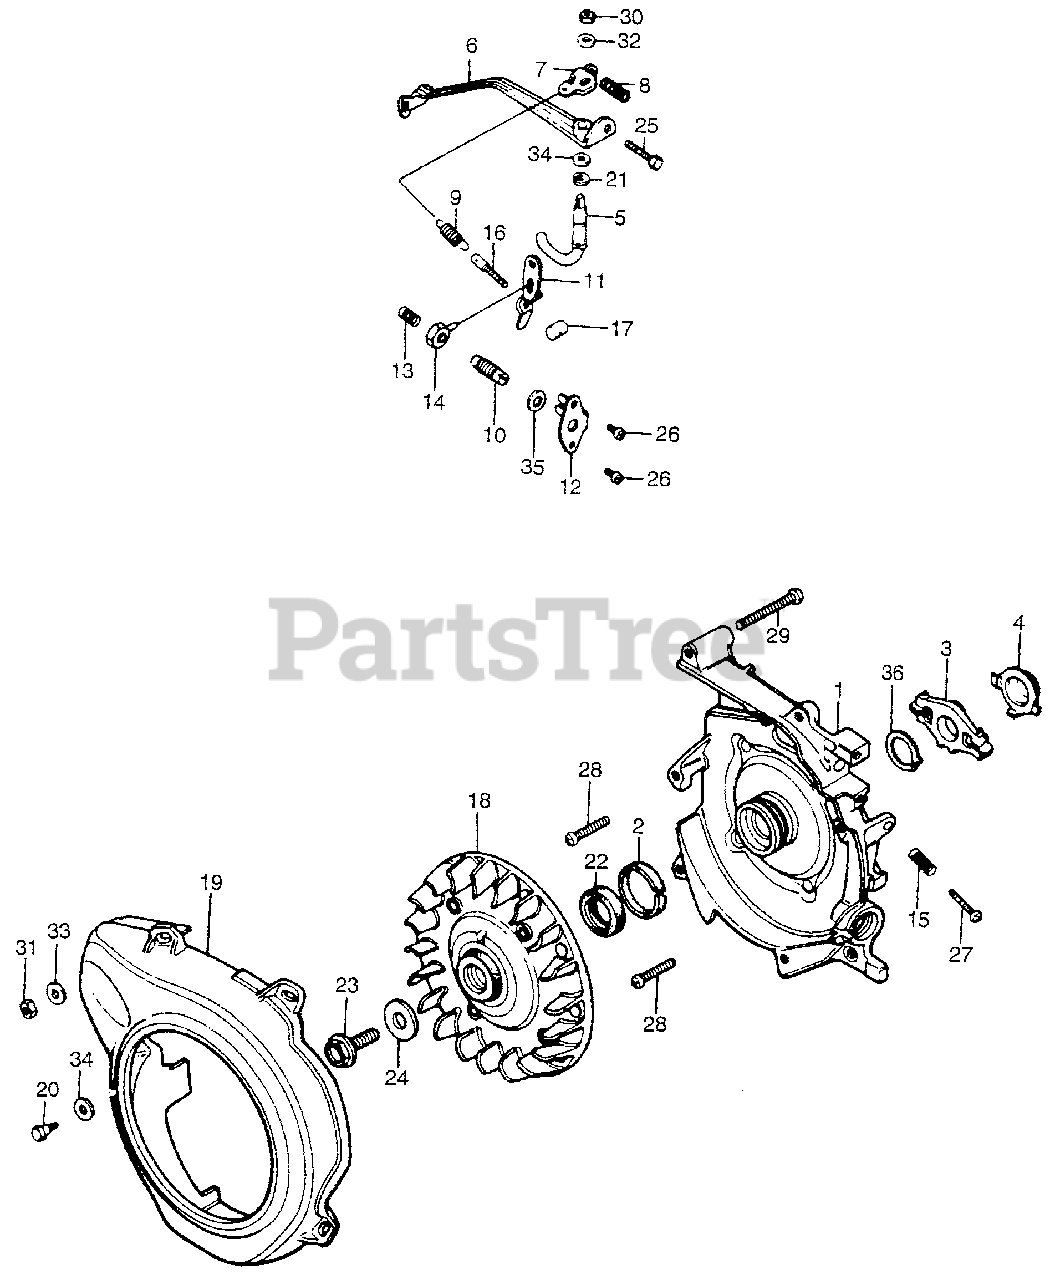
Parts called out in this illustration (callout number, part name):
1	CASE, STARTER
2	FELT (4.5MM)
3	HOLDER, GOVERNOR WEIGHT
4	SLIDER, GOVERNOR
5	SHAFT, GOVERNOR ARM
6	ARM, GOVERNOR (NOT AVAILABLE)
7	PLATE, GOVERNOR ADJUST
8	SPRING, GOVERNOR ARM ADJUST
9	SPRING, GOVERNOR
10	SHAFT, CONTROL ADJUST
11	ARM, CONTROL
12	RETAINER, ADJUST SHAFT
13	SPRING, ADJUST SHAFT
14	NUT, CONTROL ADJUSTING (NOT AVAILABLE)
15	SPRING, CONTROL ADJUSTING
16	BOLT, SPRING ADJUST
17	NUT, SPRING ADJUST
18	FAN, COOLING (NOT AVAILABLE)
19	COVER, FAN (NOT AVAILABLE)
20	BOLT, FAN COVER (NOT AVAILABLE)
21	E-RING (4MM)
22	OIL SEAL (15X24X5)
23	BOLT, HEX. (8X20)
24	WASHER, PLAIN (10MM)
25	BOLT, RECESSED (4X18)
26	SCREW, PAN (4X6)
27	SCREW, PAN (4X20)
28	SCREW, PAN (5X22)
29	SCREW, PAN (5X35)
30	NUT, HEX. (4MM)
31	NUT, HEX. (5MM)
32	WASHER, FLAT (4MM)
33	WASHER, PLAIN (5MM)
34	WASHER, PLAIN (5MM)
35	WASHER, PLAIN (6MM)
36	CIRCLIP, OUTER (15MM)
